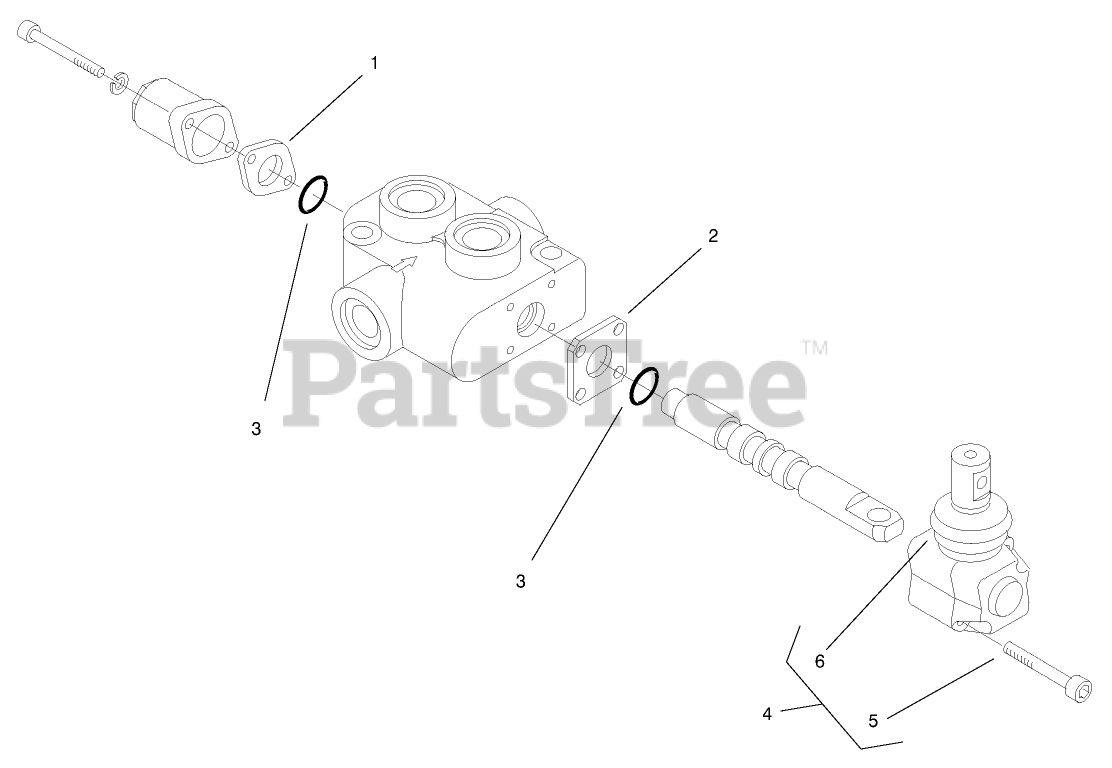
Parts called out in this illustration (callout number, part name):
1	GASKET
2	GASKET
4	OPERATOR ASM
